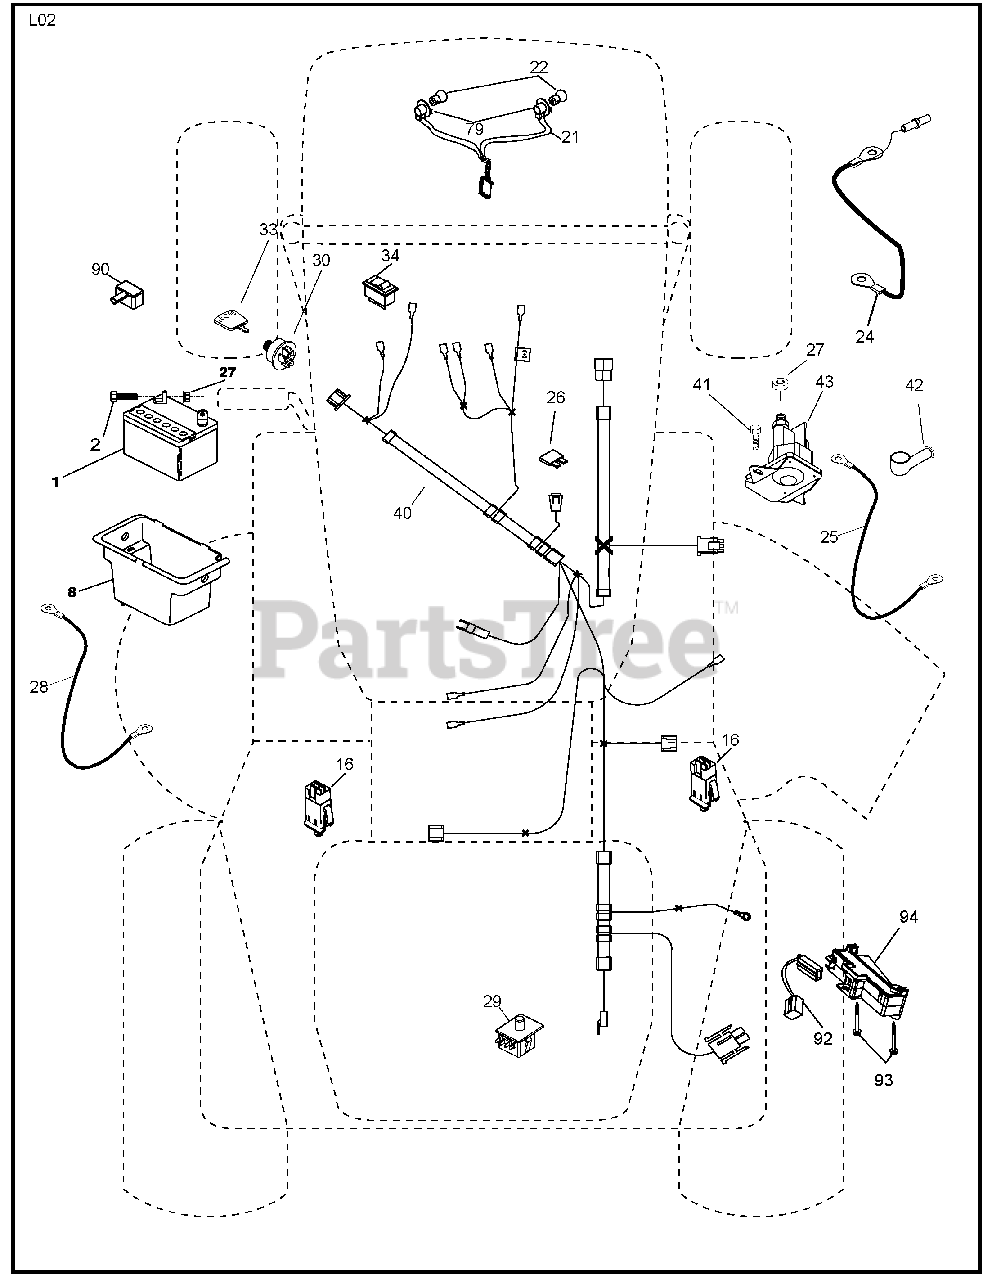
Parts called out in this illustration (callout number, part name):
1	Battery
2	Bolt Hex Hd 1/4-20 unc x 3/4
8	Box Battery
16	Switch Interlock
21	Harness Asm Light w/4152J
22	Bulb Light #1156
24	Cable Battery
25	Cable Battery 6 Ga. 11" Red Starter
26	Fuse 20 AMP
27	Nut Keps Hex 1/4-20 unc
28	Cable Ground 6 Ga. 12" Black
29	Switch Seat
30	Switch Ign
33	Key/Chain
34	Switch Light/Reset
40	Harness Ign
41	Bolt Blk Fin Hex 1/4-20
42	Cover Terminal Red
43	Solenoid
79	Socket Asm. Bulb
90	Cover Terminal Battery
92	Harness Pigtail
93	Screw Plastite 10-14 x 2.0
94	Module Reverse
